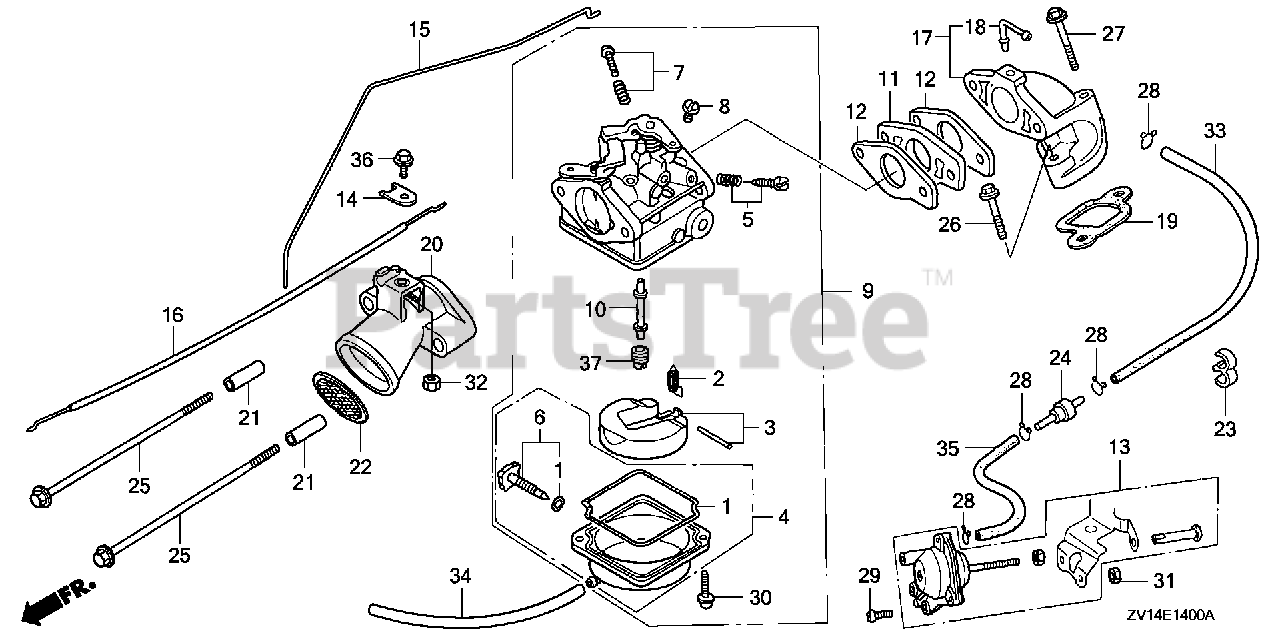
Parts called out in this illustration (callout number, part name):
1	GASKET SET
2	VALVE SET, FLOAT
3	FLOAT SET
4	CHAMBER SET, FLOAT
6	SCREW SET, DRAIN
7	SCREW SET
9	CARBURETOR ASSY. (BC05C A)
9	CARBURETOR ASSY. (BC05C B)
10	NOZZLE, MAIN
11	INSULATOR, CARBURETOR
12	GASKET, CARBURETOR
14	HOLDER, CABLE
15	ROD, THROTTLE
16	CABLE, CHOKE
17	MANIFOLD, IN. *NH8* (DARK GRAY)
19	GASKET, IN. MANIFOLD
20	GUIDE, AIR
21	COLLAR, DISTANCE
22	TRAP, FLAME
25	BOLT, FLANGE (6X102)
26	BOLT, FLANGE (6X28)
27	BOLT, FLANGE (6X42)
30	SCREW, PAN
32	NUT, HEX. (6MM)
34	BULK HOSE, VINYL (3.5X6.5X8000) (3.5X6.5)
36	BOLT, FLANGE (6X12)
37	JET, MAIN (#75)
37	JET, MAIN (#70)
37	JET, MAIN (#72)
